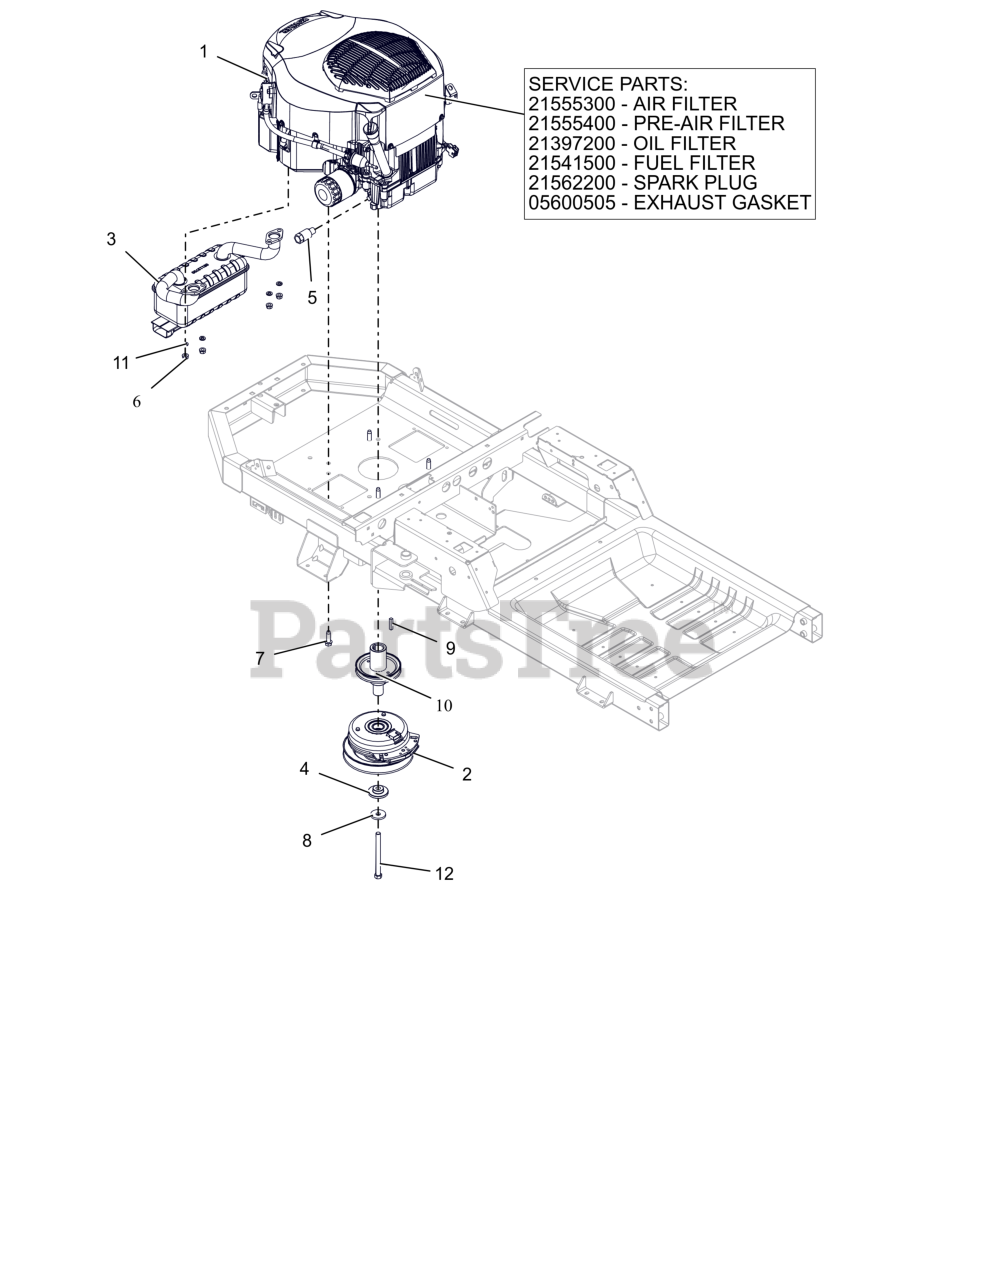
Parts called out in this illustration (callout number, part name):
1	ENGINE,KOHLER TWIN 25 PRO W/SC
1	AIR FILTER, KOHLER
1	PRE CLEANER, KOHLER
1	FILTER, OIL - KOH CV20
1	FILTER, FUEL
1	PLUG, SPARK (RFI)
1	GASKET, MUFFLER KOHLER TWIN
2	CLUTCH,105FTLB MONOPOLE 6.83"
3	MUFFLER, KOHLER
4	BSHG-FLG .469X1.06X.574X2.0
5	DRAIN, OIL
6	NUT-LK-TOP-FLG .312-18 GF ZCC
7	SCR,TAP .375-16X1.25HWH TR ZCC
8	WASHER, 7/16" SPRING DISK
9	KEY-SQ .25 X 1.25 X .25 SAE
10	WLDMT, DRIVE SHEAVE (LG XL)CZC
11	WSHR,LK-REG .312X.078 ZCC
12	BLT, HEX .44-20X5.00 G8 ZCC NT
